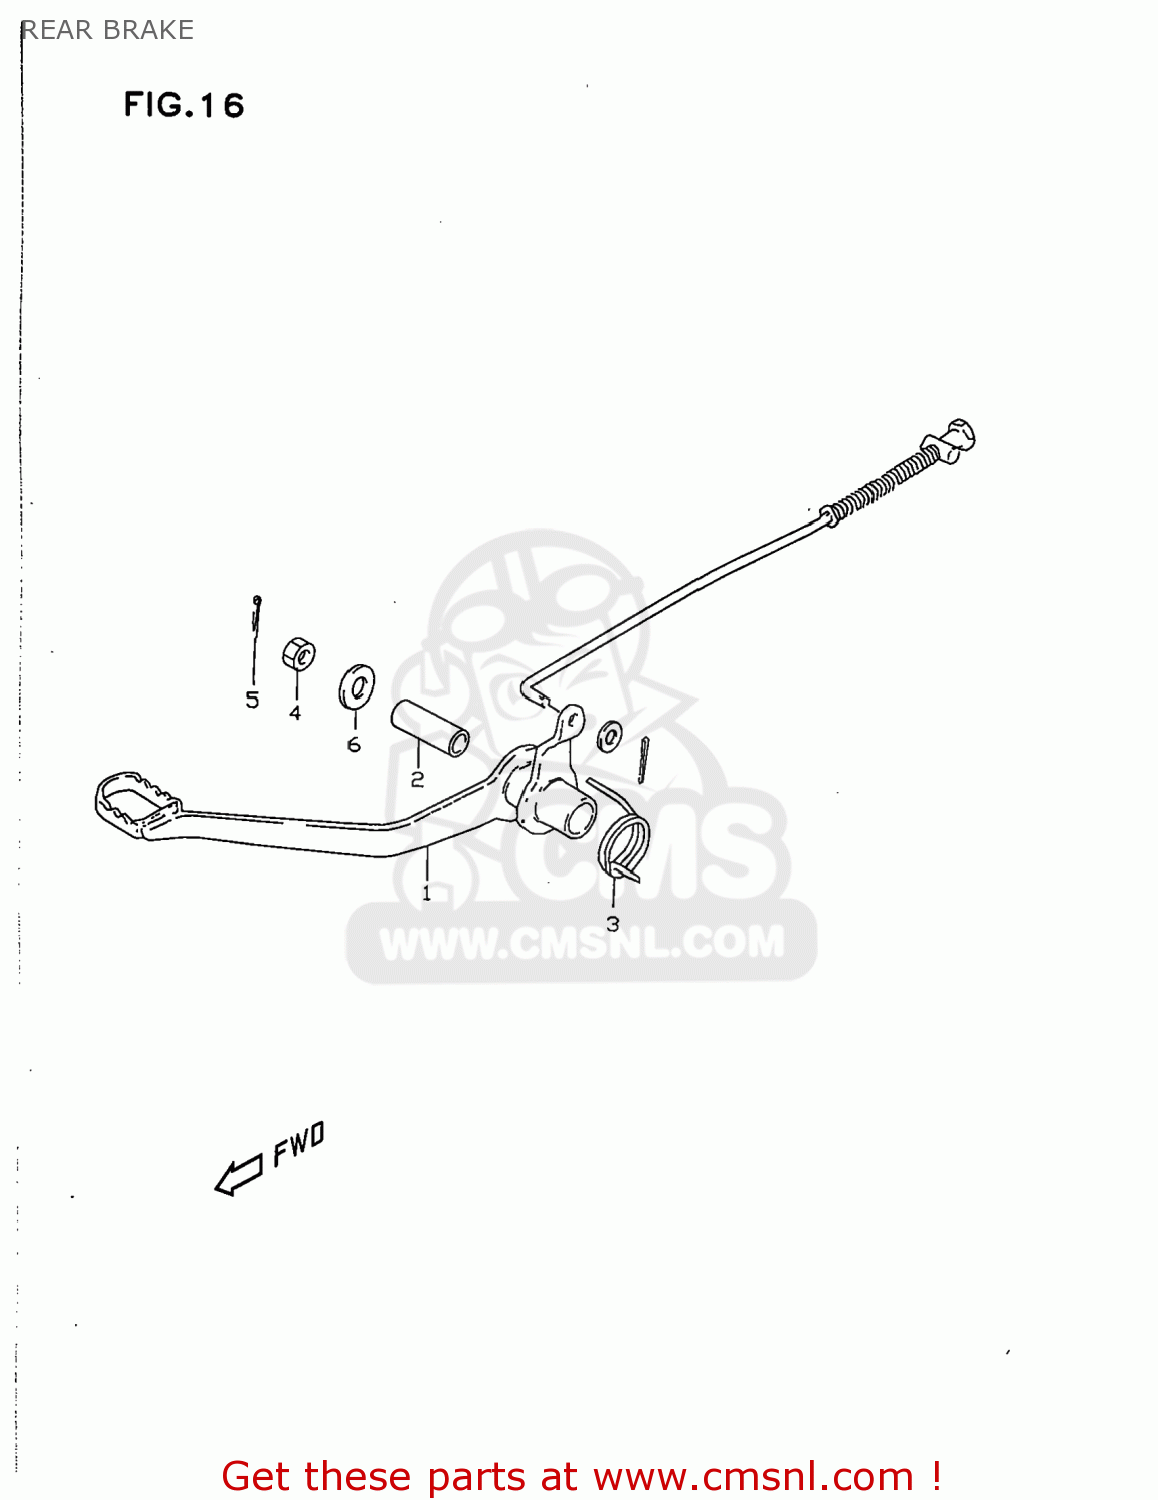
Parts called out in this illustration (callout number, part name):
1	PEDAL,BRAKE
2	SPACER,BRAKE PEDAL
3	SPRING,BRAKE PEDAL RETURN
4	NUT
5	PIN 25X20
6	WASHER(10.5X22X1.6)
